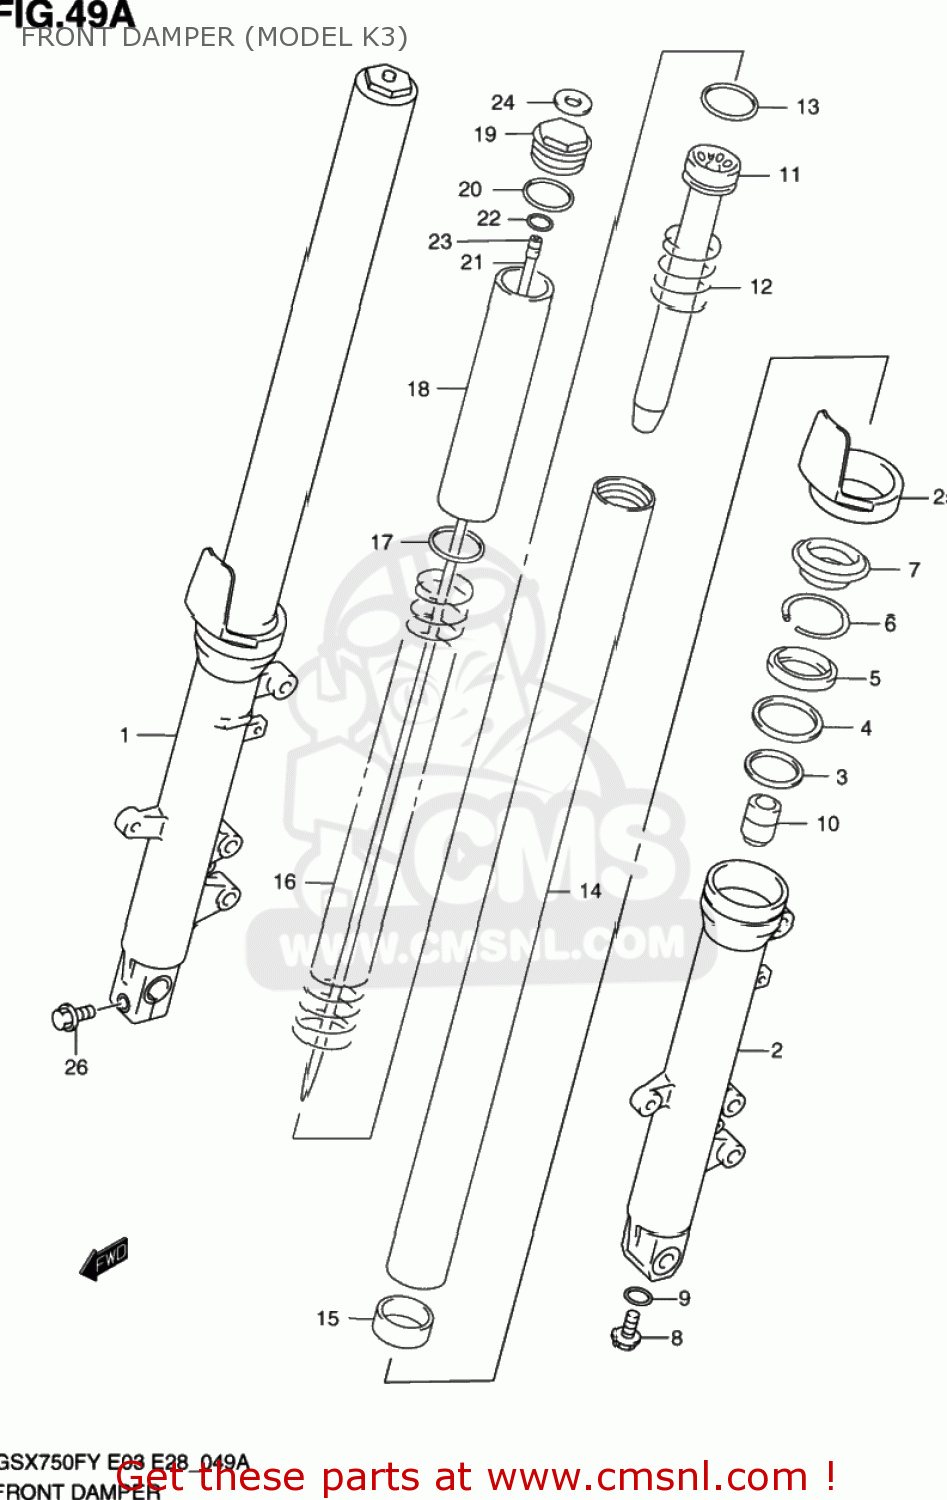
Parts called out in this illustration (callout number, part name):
1	TUBE,OUTER,R
2	TUBE,OUTER,L
3	BUSH,GUIDE
4	SPACER,SEAL
5	SEAL,OIL
6	CIRCLIP,FORK OIL SEAL
7	SEAL,DUST
8	BOLT(8X27)
9	GASKET (NAS)
10	PIECE,OIL LOCK
11	SEAT,UNDER
12	SPRING,REBOUND
13	RING,PISTON
14	TUBE,INNER
15	BUSH,SLIDE
16	SPRING,FR
17	JOINT,SPRING
18	COLLAR,SPRING
19	BOLT,FORK
20	O RING
21	ROD,DAMPER
22	O RING(D:1.9,ID:3.8)
23	RING,STOPPER(ID:6.1,D:0.6)
24	LABEL,S-H
25	PROTECTOR
26	BOLT
